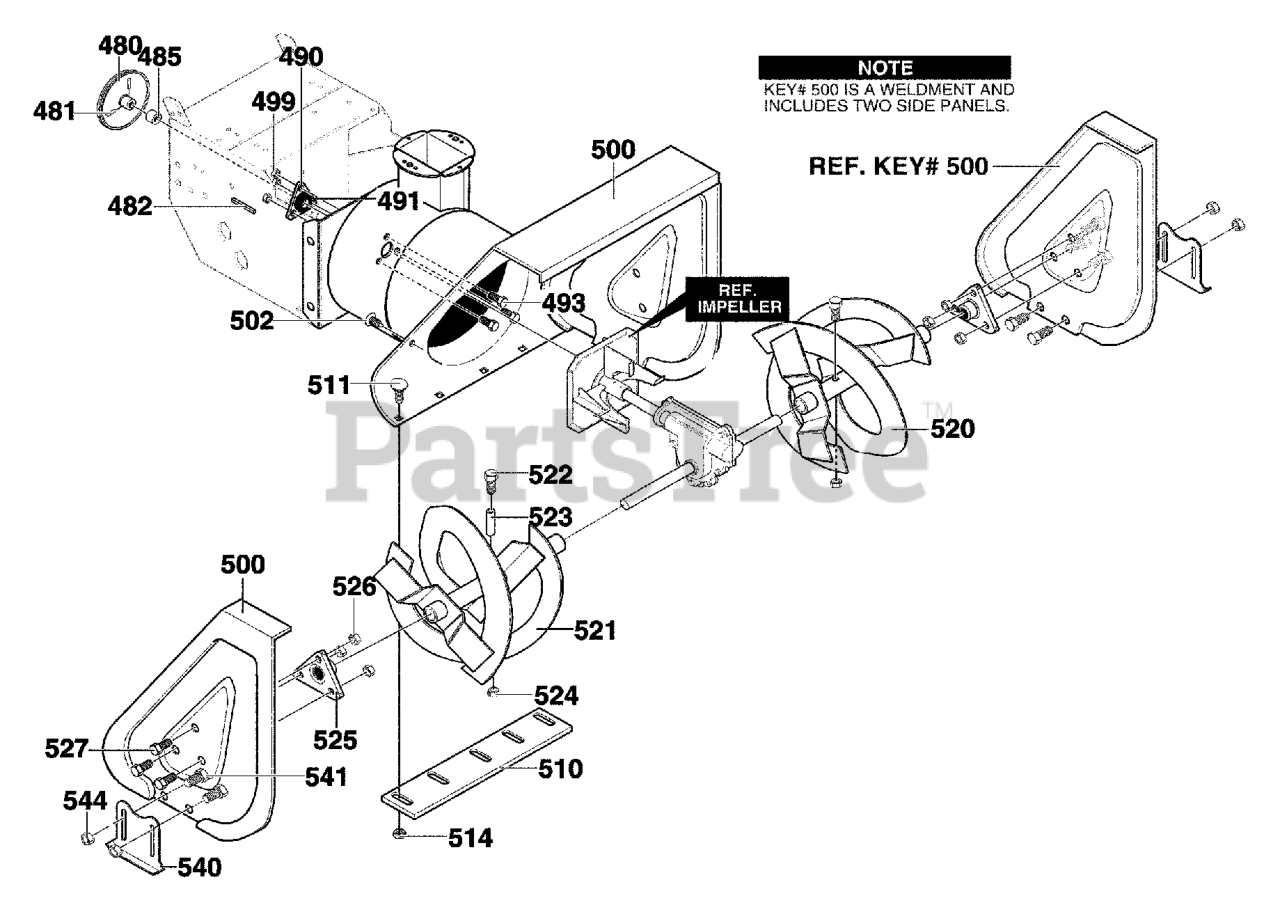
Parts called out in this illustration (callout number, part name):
480	PULLEY, 4L 6.12X .67
481	SCREW, 5/16-18 x 0.63
482	KEY, SQUARE
485	SPACER, SLEEVE .676X1.00X.53
490	RETAINER, BALL BRNG
491	BEARING, BALL
493	SCREW, 5/16-18 x 0.75
499	NUT, 5/16-18 HEXWDFLLK
500	HOUSING, ASSY
502	FASTENER, RATCHET
510	BLADE, SCRAPER 24"
511	BOLT, 1/4-20X.75
514	NUT, 1/4-20
520	AUGER, ASSY, LH
521	AUGER, ASSY, RH
522	SCREW, 1/4-20X1.75
523	SPACER, SLEEVE
524	NUT, 1/4-20 REGHEXCTRLK
525	BEARING,FLANGE
526	NUT, 5/16-18
527	SCREW, 5/16-18 x 0.75
540	SKID, HEIGHT ADJUST
541	BOLT, 5/16-18 X .75
544	NUT, 5/16-18 REGHEX
